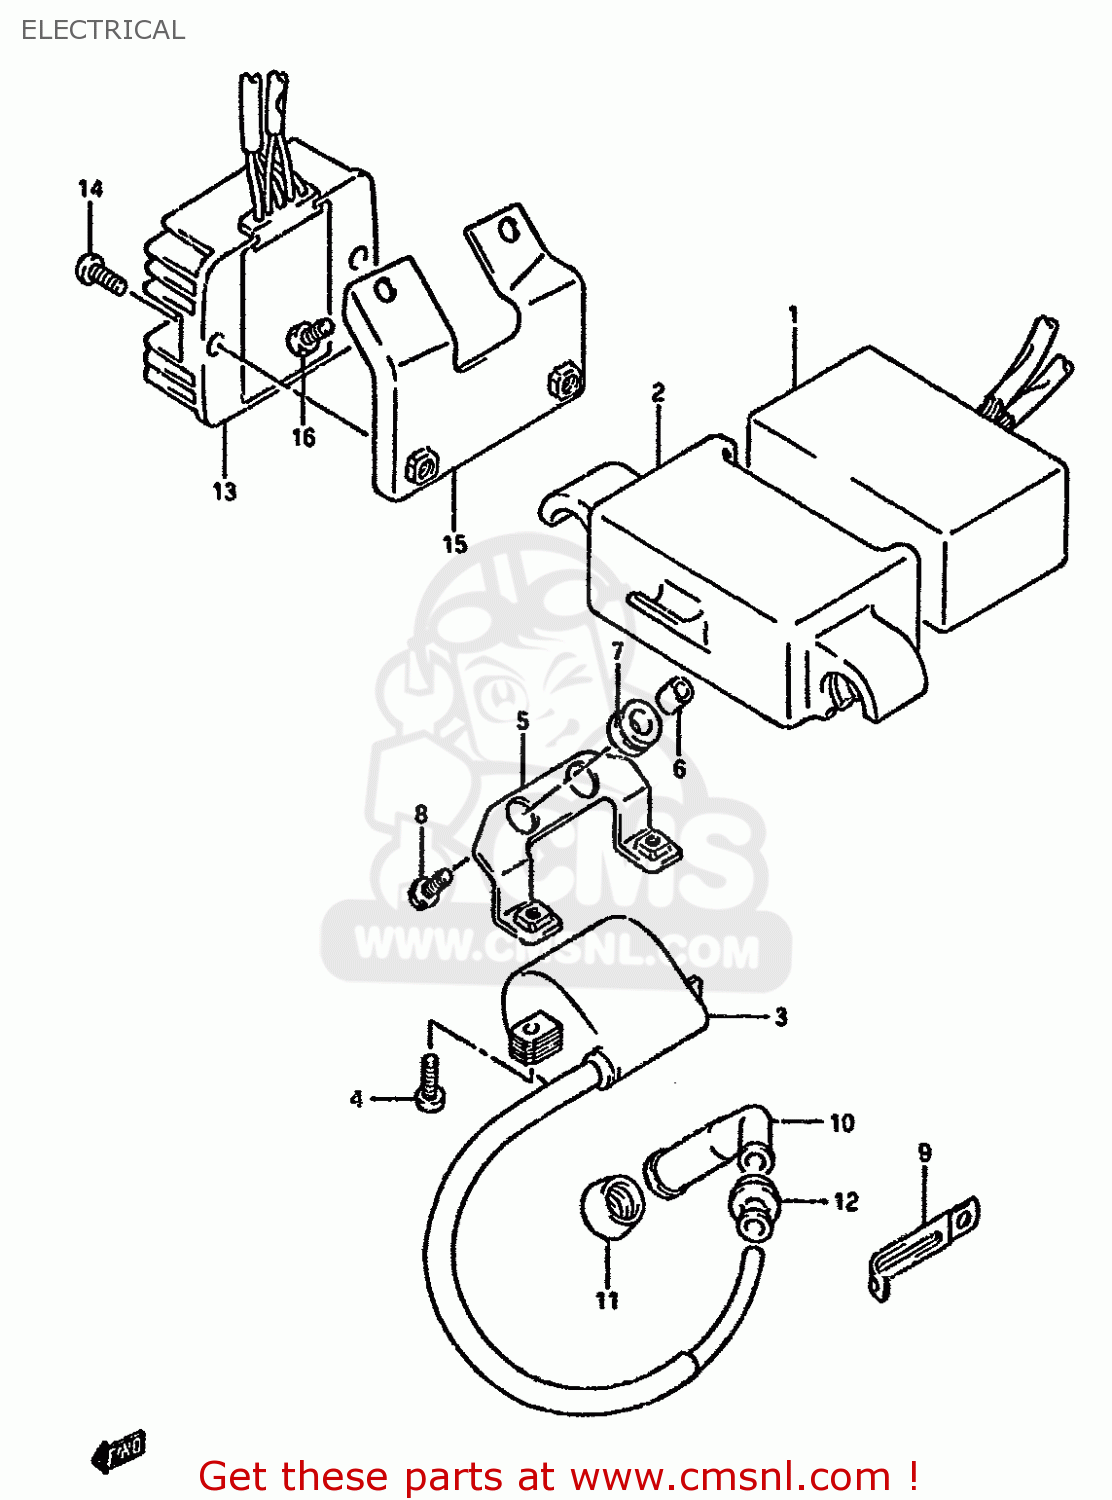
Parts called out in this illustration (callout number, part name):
1	CDI UNIT
2	CUSHION,CDI UNIT
3	COIL ASSY,IGNITION
4	SCREW
5	BRACKET,IGNITION COIL
6	SPACER (6.3X9.1X6.7)
7	CUSHION
8	BOLT
9	CLAMP
10	CAP,SPARK PLUG
11	SEAL,SPARK PLUG
12	SEAL,HIGH TENSION CORD
13	RECTIFIER ASSEMBLY
14	SCREW
15	BRACKET,RECTIFIER
16	BOLT
